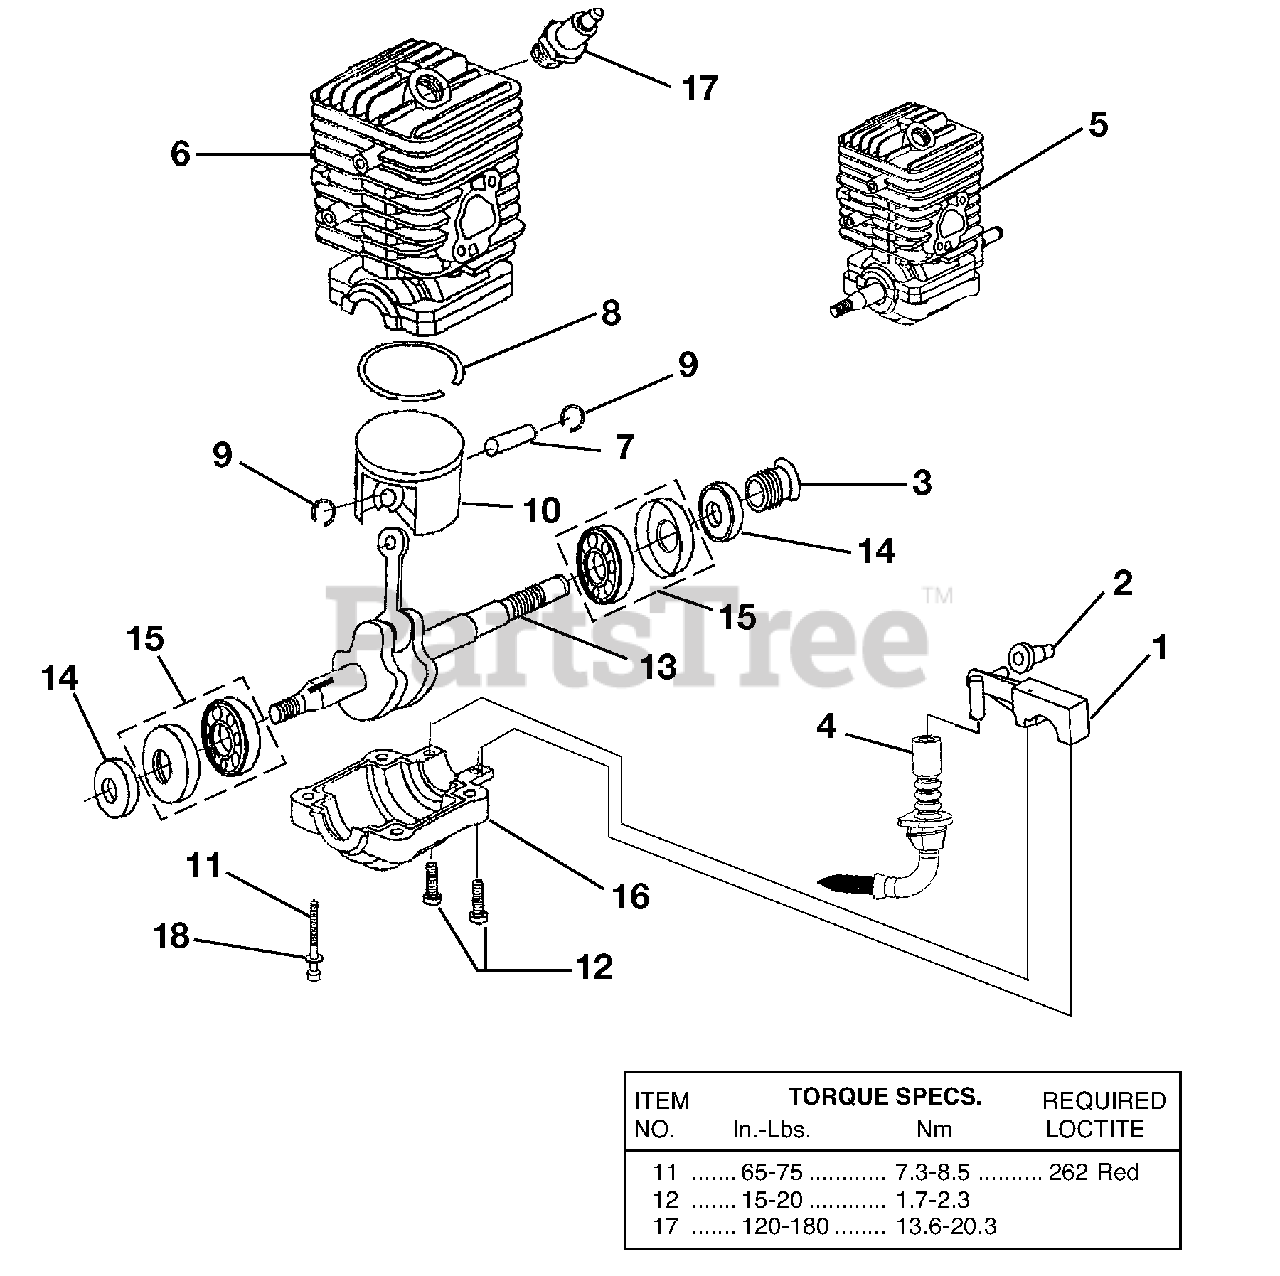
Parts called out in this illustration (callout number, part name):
1	Oil Pump Kit
2	Grommet, Oil Outlet
3	Left Hand Worm
4	Oil Intake Tube w/Filter
5	Short Block, Complete
6	Cylinder Kit
7	Piston Pin
8	Piston Ring
9	Ring, Retaining
11	Screw, Cap-Socket Hd. (10-24x2")
12	Screw, Pan Hd., (8-32x5/8")
13	Crankshaft & Rod Assembly
14	Shaft Seal
15	Bearing & Rubber Case
16	Lower Crankcase
17	Spark Plug
